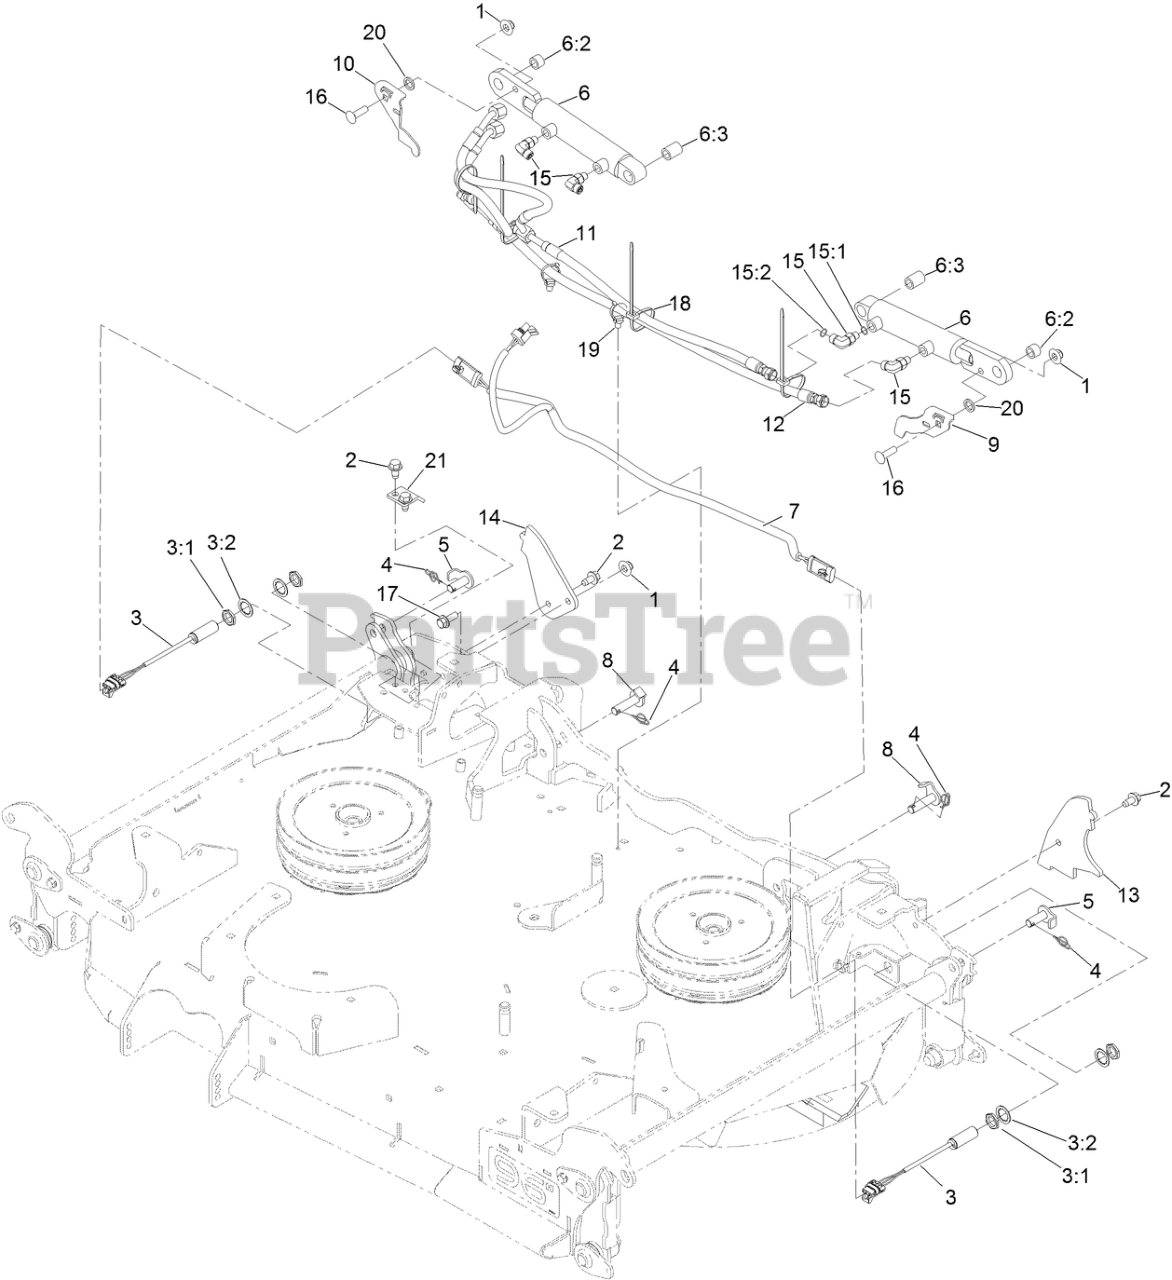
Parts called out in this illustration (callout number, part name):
1	NUT-FLANGE, NI
2	SCREW-HWH
3	PROXIMITY SWITCH ASM
3:1	NUT-HEX
3:2	WASHER-LOCK, INTERNAL TOOTH
4	PIN-COTTER, LOCKING
5	EYE-PIN, CYLINDER
6	DECK FOLD CYLINDER ASM
6:2	BUSHING
6:3	BUSHING
7	HARNESS-WIRE
8	PIN-CYLINDER
9	PLATE-PROXIMITY, LH
10	PLATE-PROXIMITY, RH
11	HOSE ASM
12	HOSE ASM
13	BRACKET-DECK STOP, LH
14	BRACKET-DECK STOP, RH
15	FITTING-ELBOW, 90 DEG
15:1	O-RING
15:2	O-RING
16	SCREW-CARR
17	SCREW-HHF
18	TIE-CABLE
19	CLIP-TIE
20	WASHER
21	BRACKET-GUARD, SWITCH (RH)
